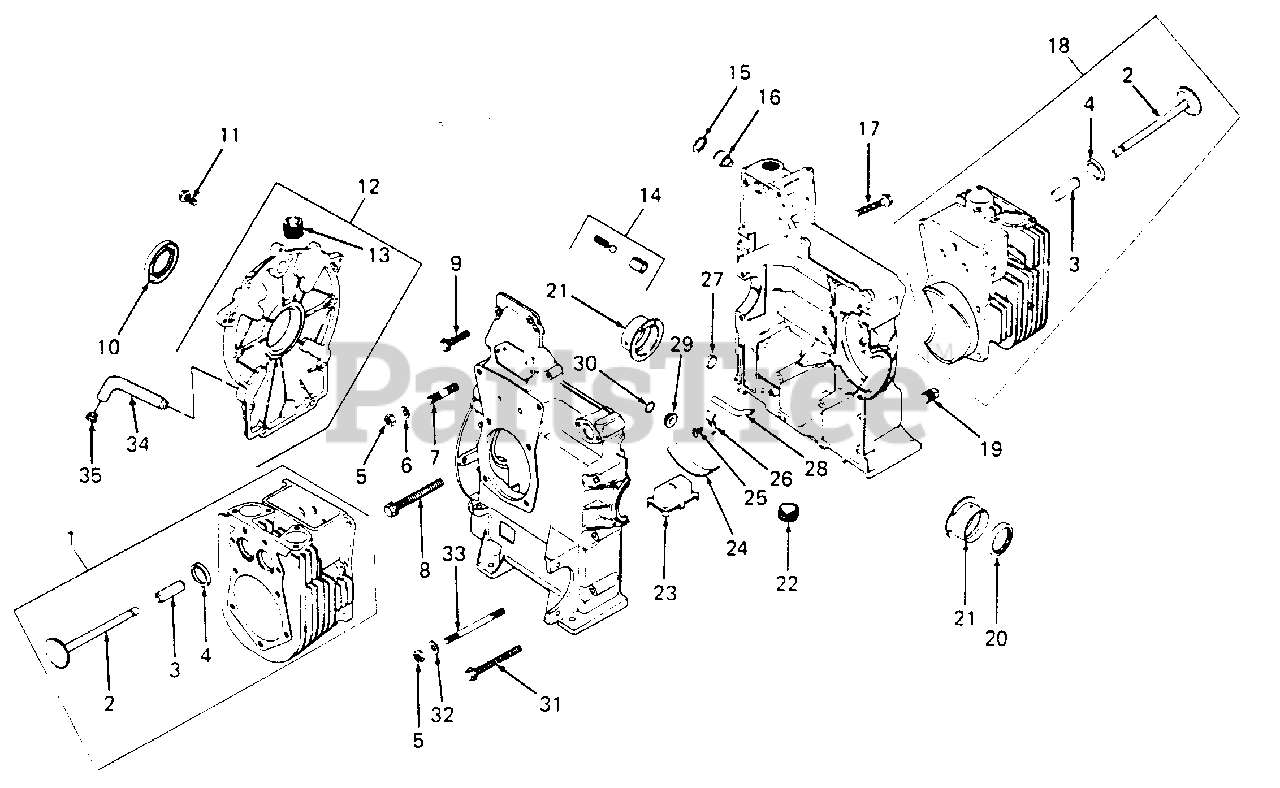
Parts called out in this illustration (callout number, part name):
1	Kit, #2 Cylinder Barrel
2	Valve, Exhaust
3	Guide, Valve
4	Insert, Valve Seat
5	Nut, Hex, 5/16-18
6	Washer, Flat, 5/16
7	Stud, Step, 5/16-18 X .75, 3/8-16
8	Screw, Hex Flange, 3/8-16 X 3.62 Lg
9	Screw, Hex Flange, 5/16-18 X 1.5 Lg
10	Seal, Rear Oil
11	Screw, Wash Hd, 5/16-18 X 1.0 Lg
12	Kit, Closure Plate
13	Plug, Hex Ctsk, 1/8 NPTF
14	Kit, Oil Relief
15	Ring, Retaining
16	Shaft, Governor
17	Screw, Hex Flange, 5/16-18 X 2.0 Lg
18	Kit, #1 Cylinder Barrel
19	Plug, Hex Ctsk, 3/8 NPTF
20	Seal, Front Oil
21	Bearing, Sleeve (Std)
22	Plug, Bottom Drain, 3/8
23	Housing, Oil Pickup
24	Clamp, Spring
25	Screw, Hex Wash Hd, #10-32 X .43 Lg
27	Plug, Cup
28	Tube, Oil Pickup
29	Plug, 3/4 OD
31	Screw, Hex Flange, 5/16-18 X 3.5 Lg
32	Washer, Plain
33	Stud, 5/16-18 X 4.12 Lg
34	Pipe, Oil Drain
35	Plug, Oil Drain
